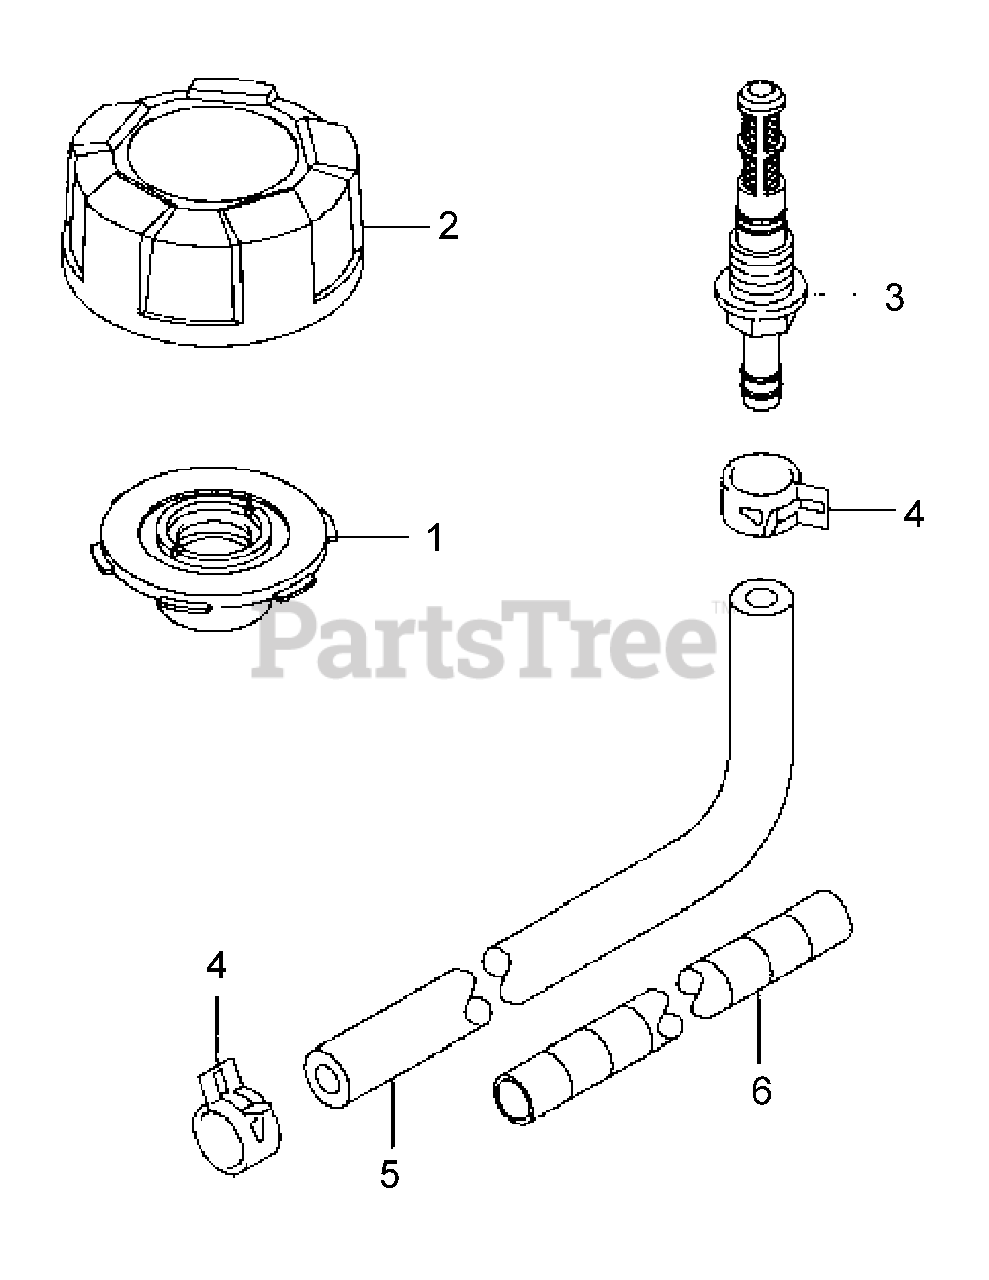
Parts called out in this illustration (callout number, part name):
2	Fuel Cap
3	Joint, In Tank Filter
4	Clamp
5	Tube, 6.35x12.7x285
